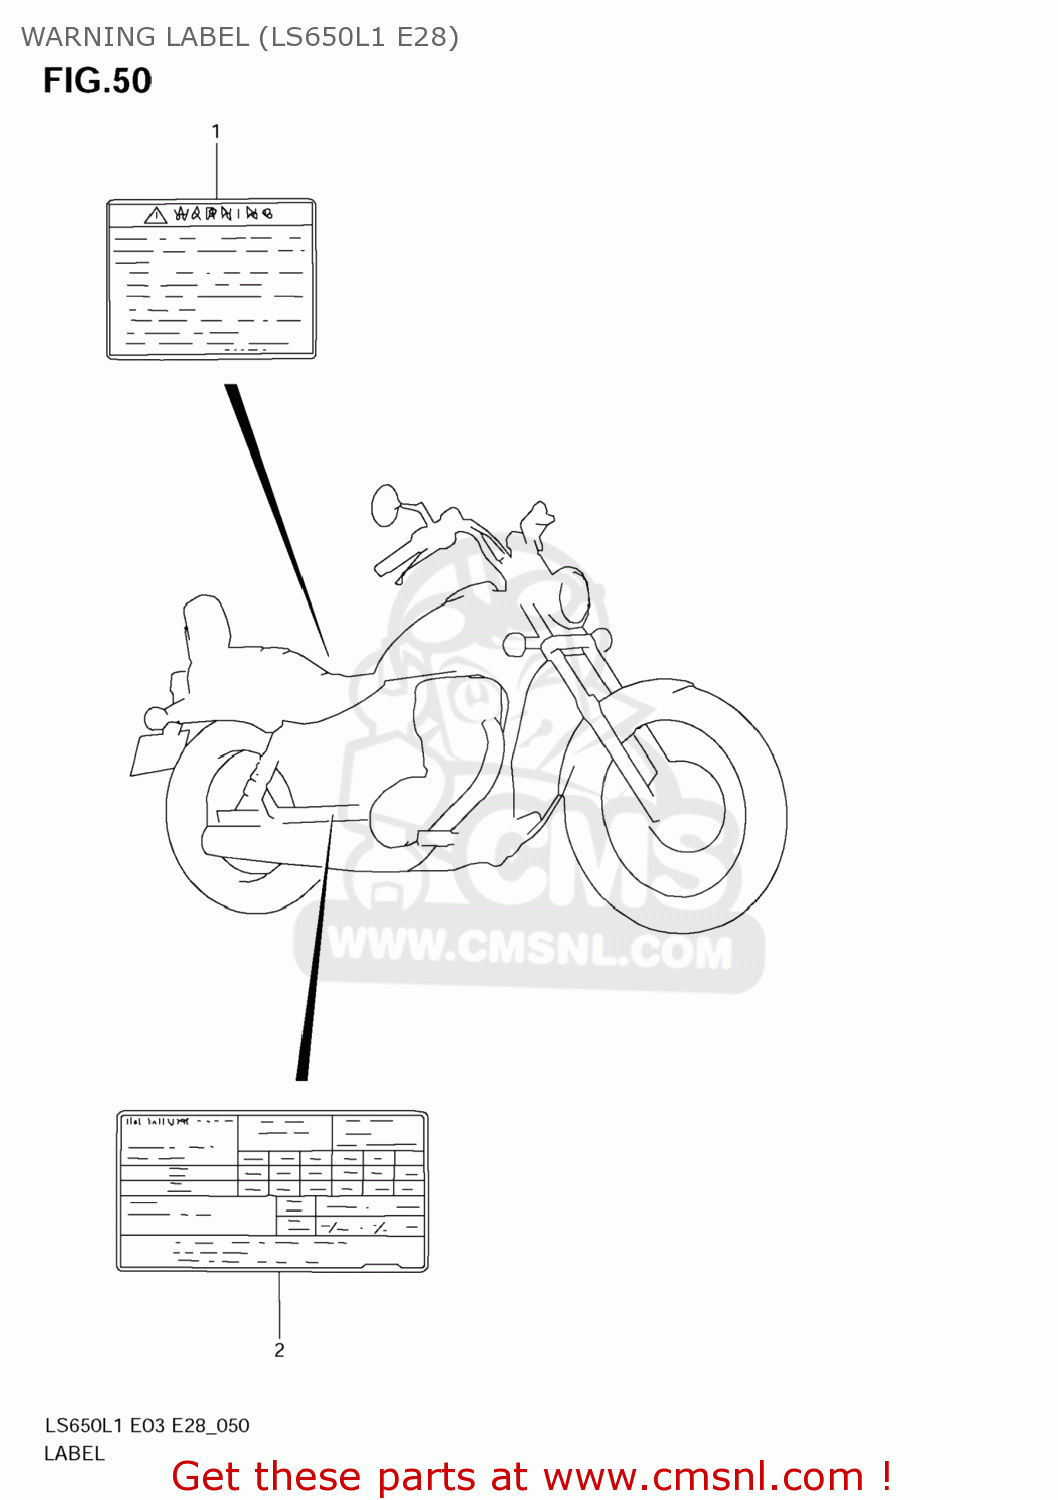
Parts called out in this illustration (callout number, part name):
1	LABEL,GENERAL WARNING
2	LABEL,TIRE INFORMATION
3	MANUAL,OWNER'S
